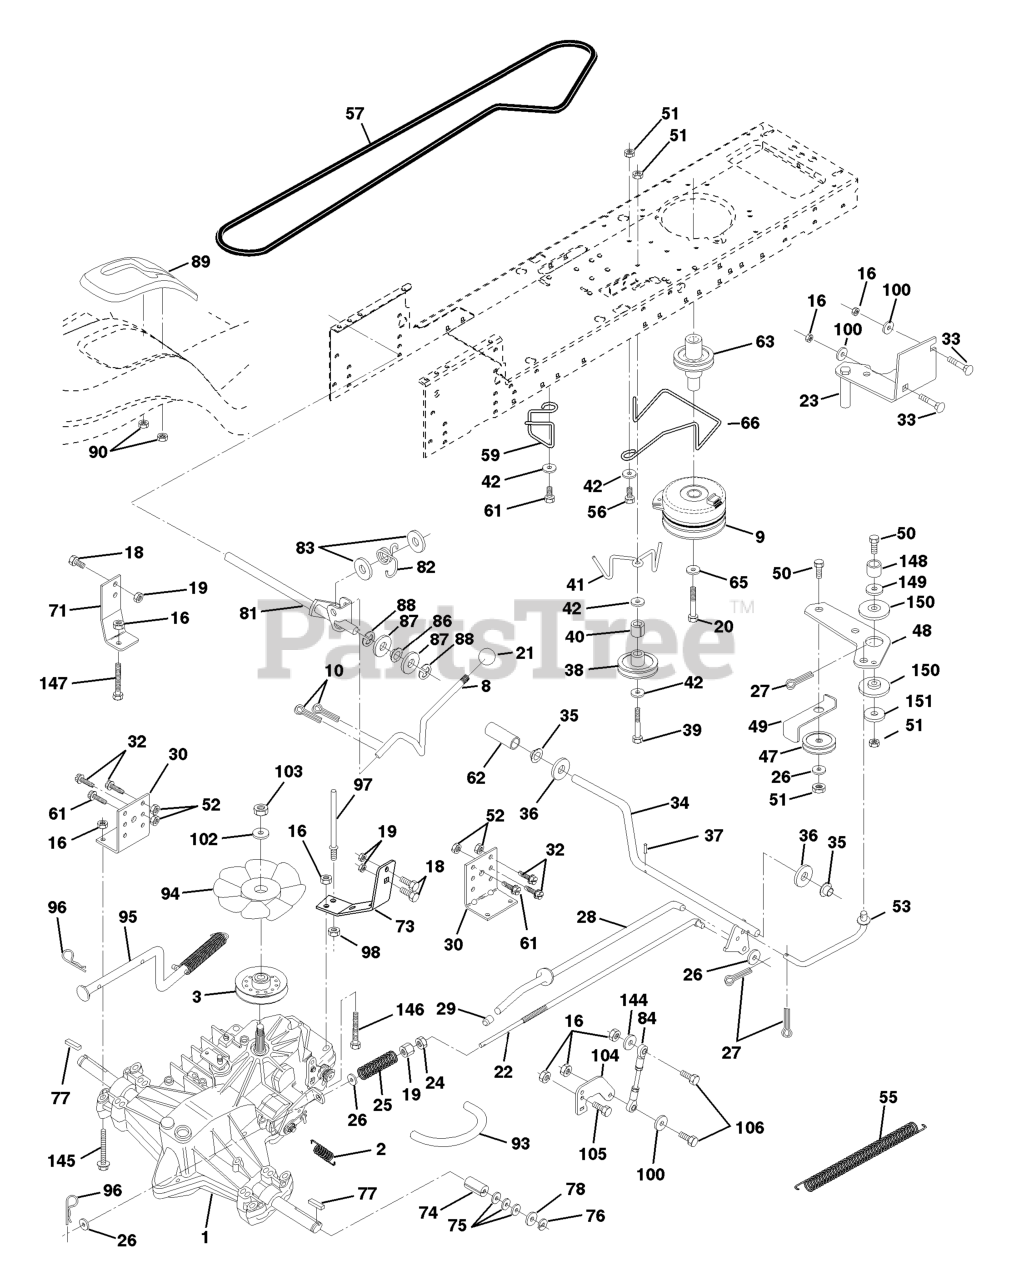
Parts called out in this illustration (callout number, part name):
1	TRANSAXLE ASSEMBLY
2	SPRING BRAKE
3	PULLEY, TRANSAXLE
8	ROD SHIFT FENDER
9	CLUTCH.ELECT.EVX.
10	PIN COTTER
15	BOLT HEX 5/16-18 GR 5
16	NUT.71038.31-18.HEX.NYLOCK
18	BOLT
19	NUT
20	BOLT HEX
21	KNOB.DELUXE.(PISTOL.GRIP).BLAC
22	ROD BRAKE HYDRO
23	BRACKET, ASM CLUTCH MTG
24	NUT
25	SPRING ROD LT
26	WASHER
27	COTTER PIN
28	ROD BRAKE PARK LT
29	PLUNGER CAP
30	BRACKET TRANSAXLE
32	BOLT
33	RP BOLT 5/16-18 X3/4 ZN/YEL GR
34	SHAFT, FOOT PEDAL
35	BEARING.NYLON
36	WASHER LT
37	DRIVE PIN
38	PULLEY.IDLER.FLAT
41	KEEPER, BELT IDLER
42	WASHER
43	WASHER T
47	IDLER PULLEY
48	BELLCRANK, CLUTCH
49	RETAIN BELT
50	BOLT
52	LOCKNUT
53	LINK, CLUTCH LT
55	SPRING, RETURN LT
57	DRIVE BELT, LTH & YTH TRACTORS
59	KEEPER CENTER SPAN
61	SCREW
62	COVER, PEDAL (1 2)
63	PULLEY, CLUTCH ELECT EVX
65	LOCKWASHER
66	KEEPER BELT ENGINE
71	STRAP LH TORQUE
73	STRAP TORQUE RH HYDRO
74	SPACER SPLIT
77	SQUARE KEY
81	SHAFT ASSY
82	SPRING,TORSION
83	WASHER
84	ROD.TIE.BALL.4.75
86	BUSHING.STEERING.ROD LTB-WSL
89	SHIFT CONSOLE
90	NUT.PUSH.3/16
91	BOLT.FIN HEX 5/16-18UNC X2 1/4
92	HEX BOLT
93	LINE FUEL HYD 4"
94	FAN 7" HYDRO
95	CONTROL ARM, BYPASS HYDRO
96	RETAINER M
97	KEEPER BELT RH
100	WASHER M
103	NUT.HEX.1/2-20
104	CONTROL ARM
106	BOLT.5/16-18X1-1/4 FULL.THREAD
144	Washer 11/32 x 5/8 x 16 Ga.
146	Bolt Hex Flghd 5/16-18 x 2-1/4
147	Bolt Hex Flghd 5/16-18 x 1-1/2
149	SPACER RETAINER
150	BUSHING NYLON COLLERED
151	WASHER 12/32X2X10GA
